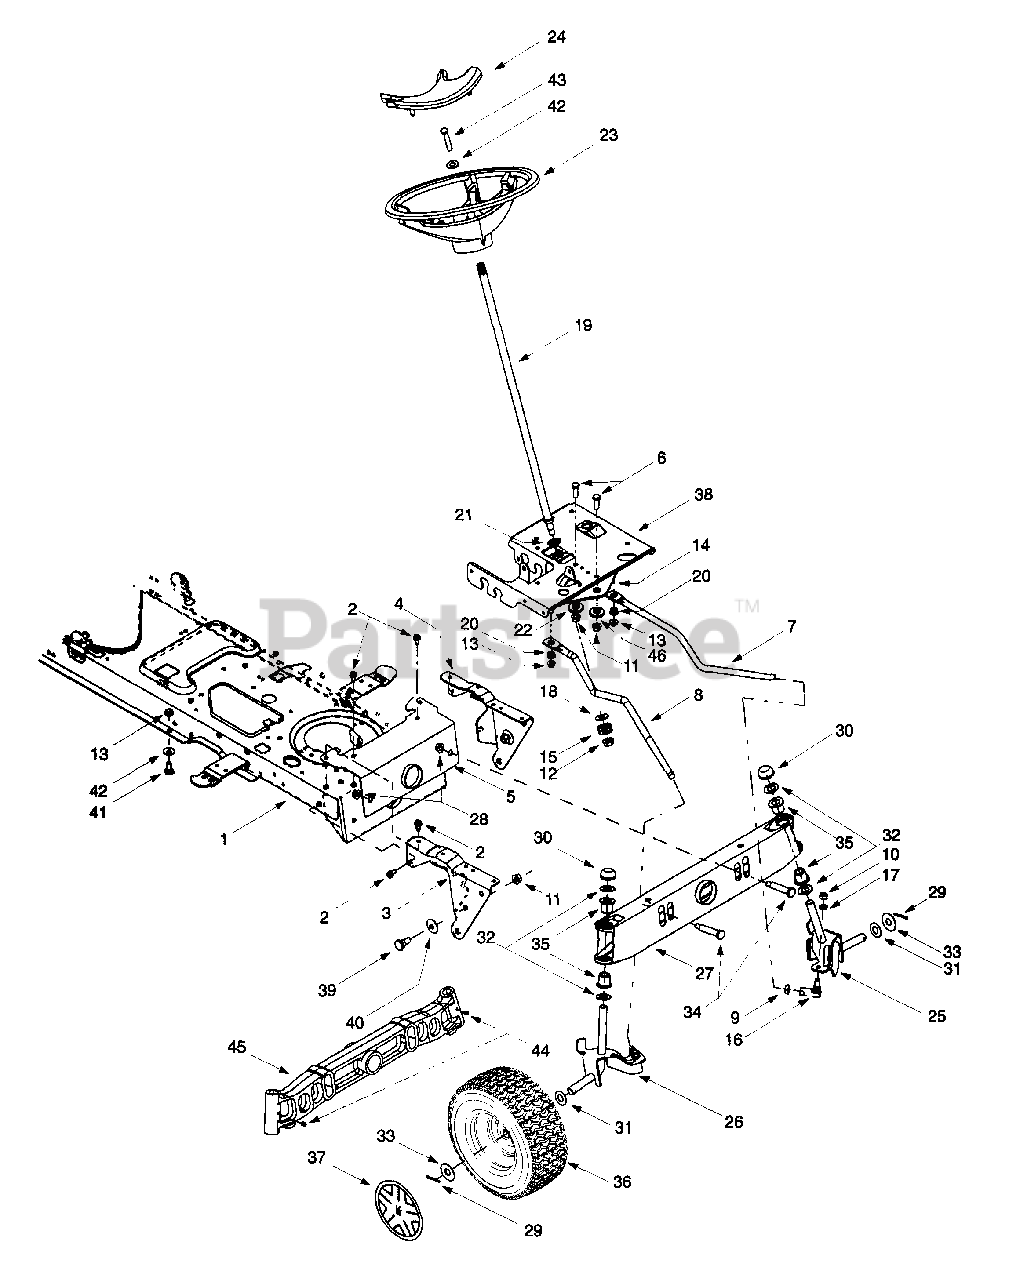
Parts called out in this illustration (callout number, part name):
6	Hex Cap Screw, 3/8-16 x 1 (Grade 5)
7	LH Drag Link
8	RH Drag Link
9	Jam Nut, 7/16-20 (Grade 2)
10	Hex Nut, 3/8-24 (Grade 2)
11	Flange Lock Nut, 3/8-16
12	Flange Lock Nut, 7/16-20
13	Flange Lock Nut, 5/16-18
14	Steering Gear, 11/90 Ratio
15	Steering Pinion Gear
16	Ball Joint, 7/16-20
17	Lock Washer, 3/8
18	Flat Washer, .51 x 1.12 x .06
19	Steering Shaft, .625 OD x 24.4
20	Plastic Bushing, .38 ID
21	Hex Flange Bearing, 5/8
22	Shoulder Spacer, .38 ID
23	Steering Wheel, .625 Spline
24	Steering Wheel Cap w/ Logo
25	LH Axle Assembly, .625 Diameter
26	RH Axle Assembly, .625 Diameter
28	Flange Lock Nut, 3/8-16
29	Cotter Pin
30	Push Cap, 5/8
31	Flat Washer, .64 x 1.0 x .12
32	Flat Washer, .64 x 1.24 x .06
33	Flat Washer, .635 x 1.589 x .06
34	Shoulder Screw, .5 x 2.2, 3/8-16
35	Flange Bearing, .632 ID x .937 OD
37	Hub Cap, Yellow w/ Spring Logo
39	Shoulder Screw, .625 x .50, 7/16-20
40	Bell Washer, .39 x 1.13 x .062
41	Shoulder Screw, .435 x .178, 5/16 x .56
42	Bell Washer, .34 x .872
43	Hex Bolt, 5/16-18 X 1
44	Grease Fitting
46	Shoulder Spacer, .38
